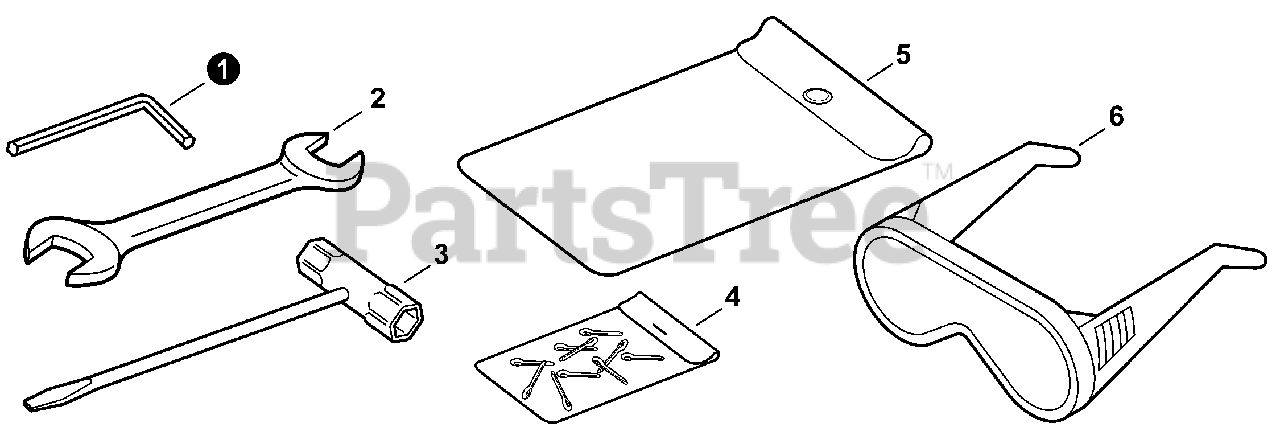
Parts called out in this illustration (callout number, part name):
1	WRENCH, ALLEN 4 MM
2	SPANNER 8×10
3	T-WRENCH 17x-19 L200
4	PIN, COTTER 2×22
5	BAG, TOOL
6	GLASSES, SAFETY
